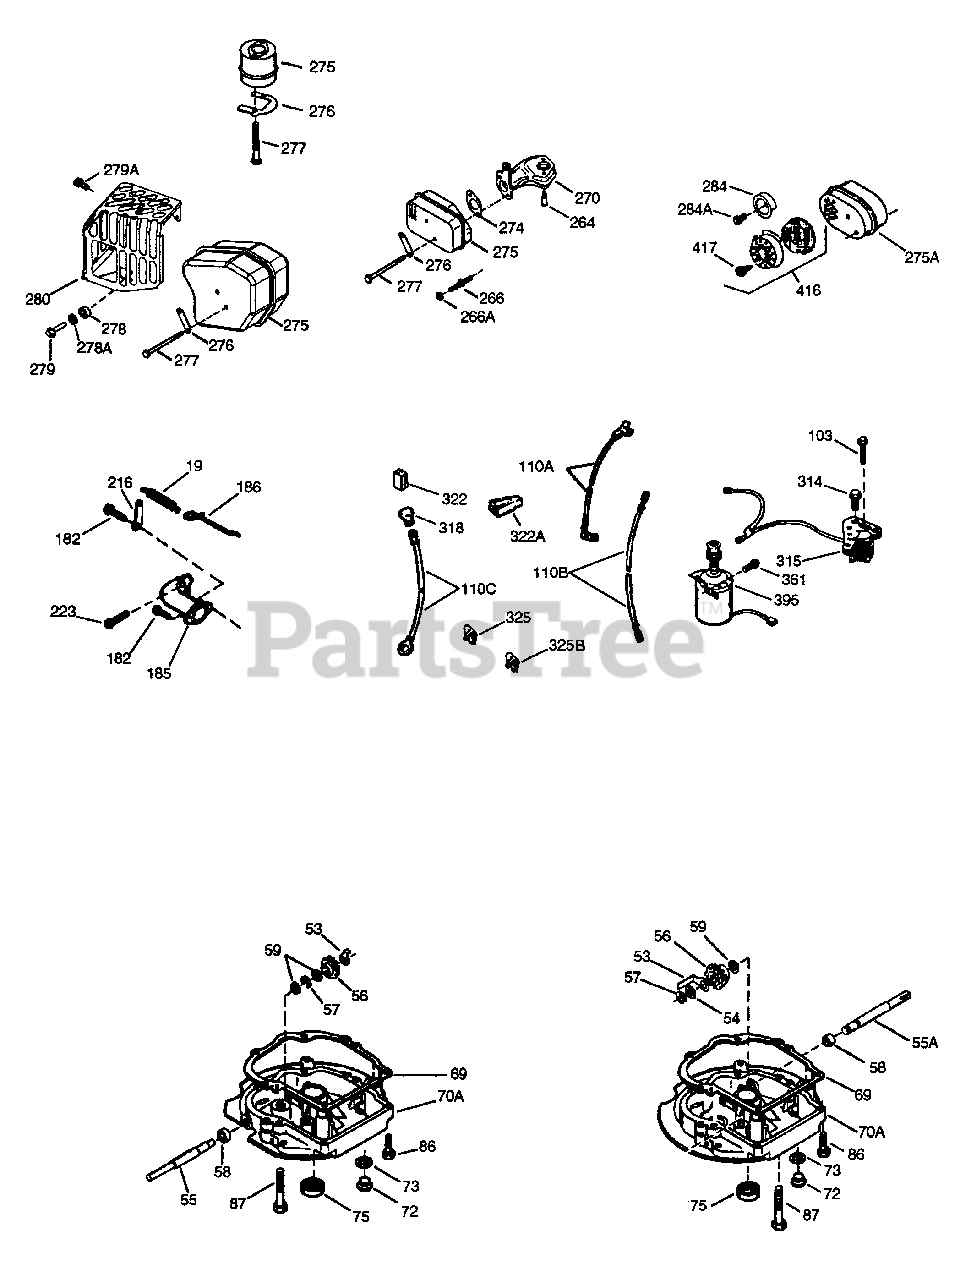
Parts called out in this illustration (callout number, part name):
19	Extension Spring
69	* Mounting Flange Gasket
72	Oil Drain Plug (Incl. 73)
73	Drain Plug Gasket
75	Oil Seal
86	Screw, 1/4-20 x 1-1/4"
103	Screw, Torx T-15, 10-24 x 15/16"
182	Screw, 1/4-28 x 1"
185	Intake Pipe
186	Governor Link
216	R.P.M. Adjusting Lever
223	Screw, 1/4-20 x 2-25/32"
275	Muffler (Incl. 276 & 277)
276	Locking Plate
277	Screw, 1/4-20 x 2-47/64"
900	Replacement Engine NONE
900	Replacement S/B 750834, order from 71 -999
999	Summer Maintenance Kit (incl. Oil, Sp ark Plug, Air Cleaner, & Ultra-Fresh)
